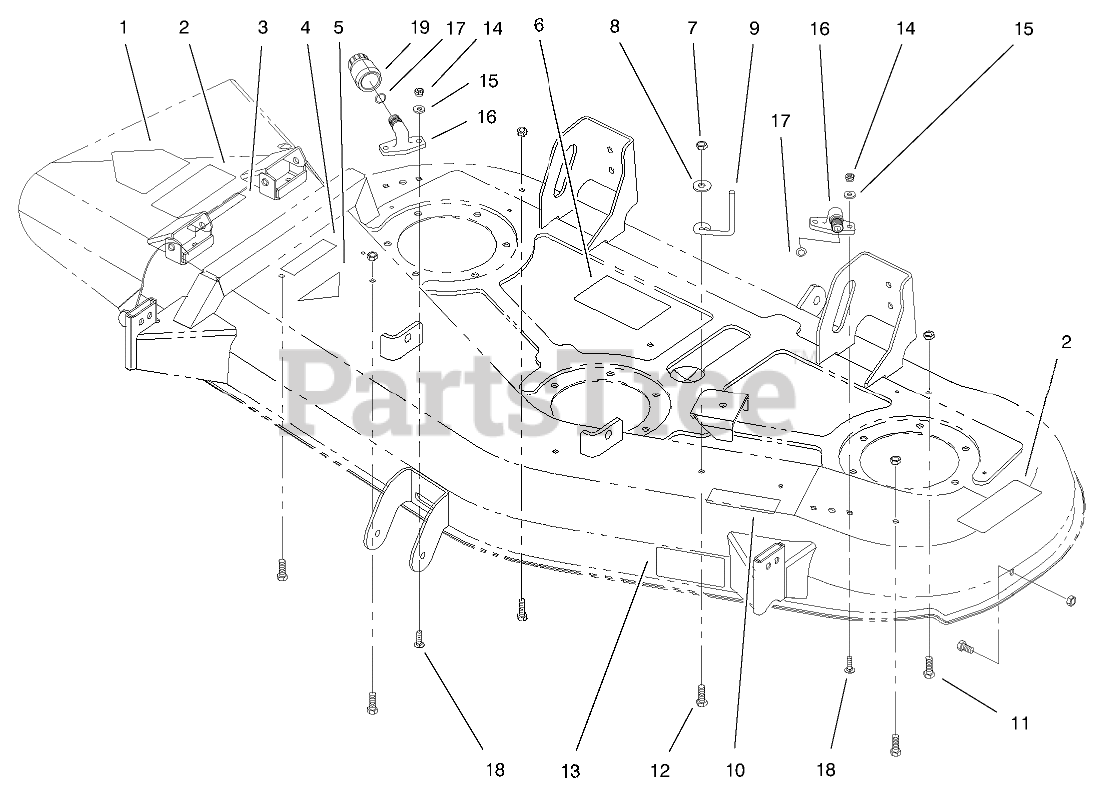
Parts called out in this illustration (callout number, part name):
1	Decal-Danger (Only On: 78280)
2	Decal-Danger (Only On: 78280)
3	Decal-Caution (Only On: 78280)
6	Decal-Belt Routing (Only On: 78280)
7	Nut-Lock NI (Only On: 78280)
8	Washer-Flat (Only On: 78280)
9	Guide-Belt (Only On: 78280)
10	Decal-Belt Routing (Only On: 78280)
11	Screw-HH (Only On: 78280)
12	Screw-HH (Only On: 78280)
13	Decal-Wheel Adjustment (Only On: 78280)
14	NUT-LOCK, NI
15	WASHER-FLAT
16	FITTING-WASHOUT
16	Screw-HH (Only On: 78285)
17	O-RING
18	BOLT-CARR
19	CONNECTOR-HOSE
